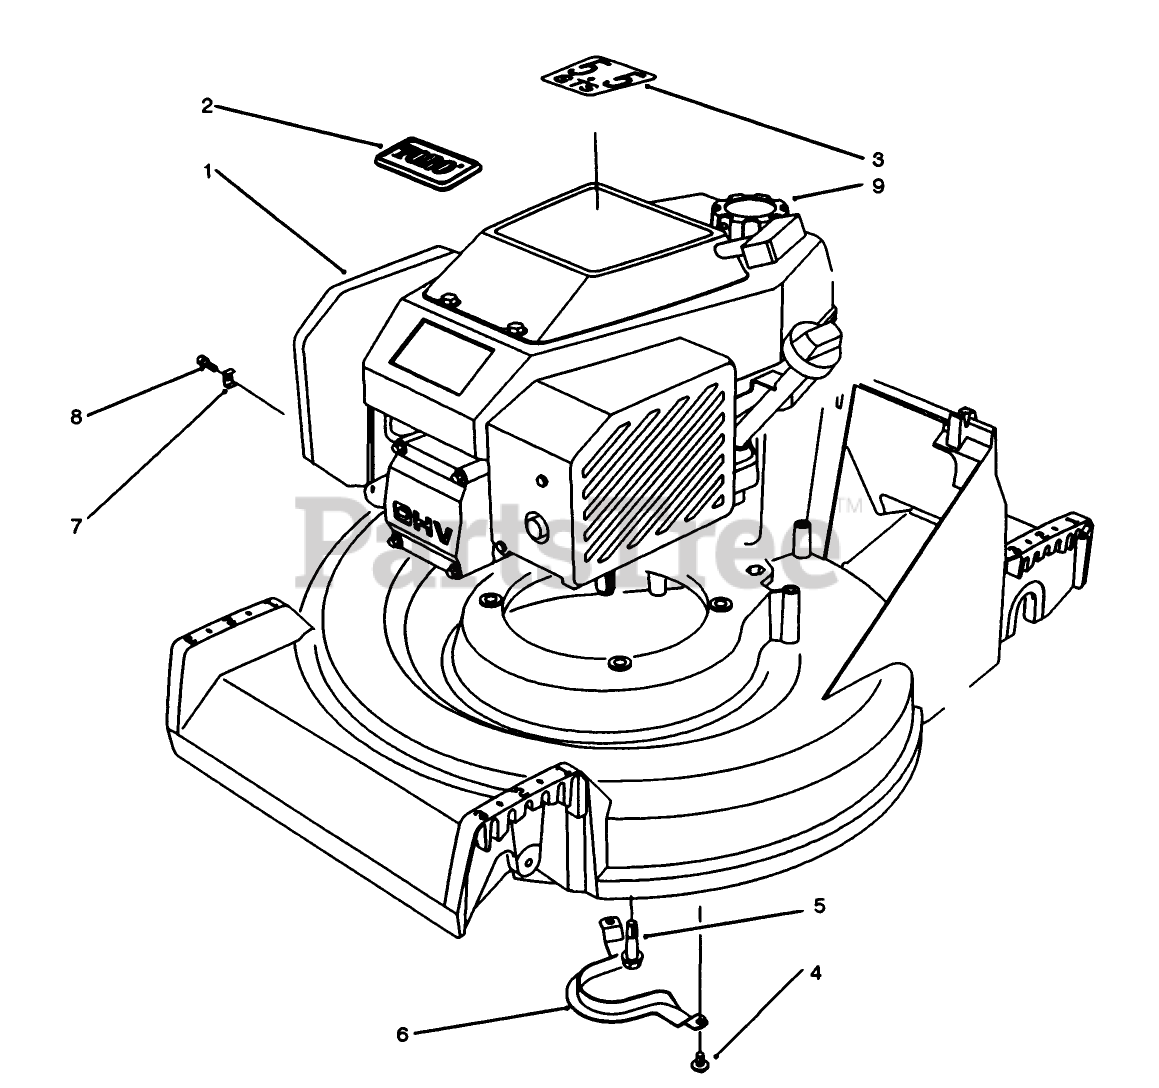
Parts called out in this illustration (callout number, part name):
1	Engine (Incl. Ref. #2 & 3)
2	TORO LOGO PLATE
3	DECAL - ENGINE
4	SCREW-HWHTF
5	SCREW-HWH
6	Guide-Belt
7	CLAMP-CASING
8	Screw
9	GAS CAP ASM
